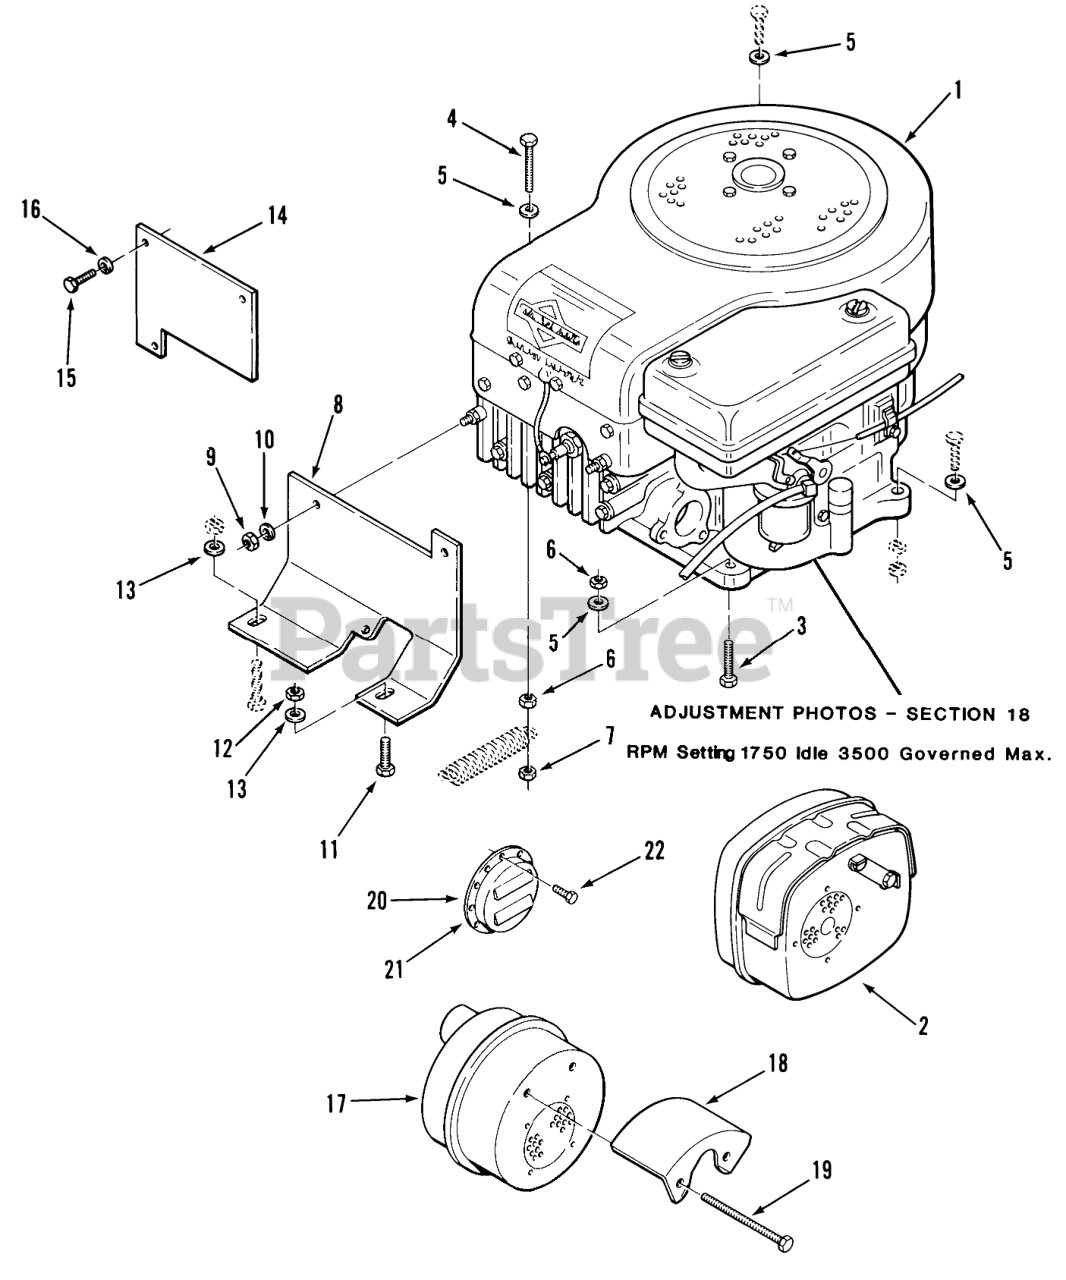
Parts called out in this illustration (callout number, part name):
1	Engine-08 HP B&S Model 190707 Type 2167-01 A-85 ONLY
1	Engine-11 HP B&S Model 252707 Type 0682-01 A-115 ONLY
2	Muffler A-85 ONLY
3	Bolt
4	Bolt 5/16-18 x 2
5	WASHER 5/16 SAE
6	Nut
7	Nut
8	BRACKET ENGINE HE R
9	Nut
10	Lockwasher
11	Bolt
12	NUT
13	Washer
14	PLATE SPRING B
15	Bolt
16	Washer
17	Muffler With Shield A-115 ONLY
18	Heat Shield A-115 ONLY
19	Bolt, 5/16-18 x 1/4
20	Louvered Deflector A-115 ONLY
21	Louvered Deflector A-85 ONLY
22	Screw
